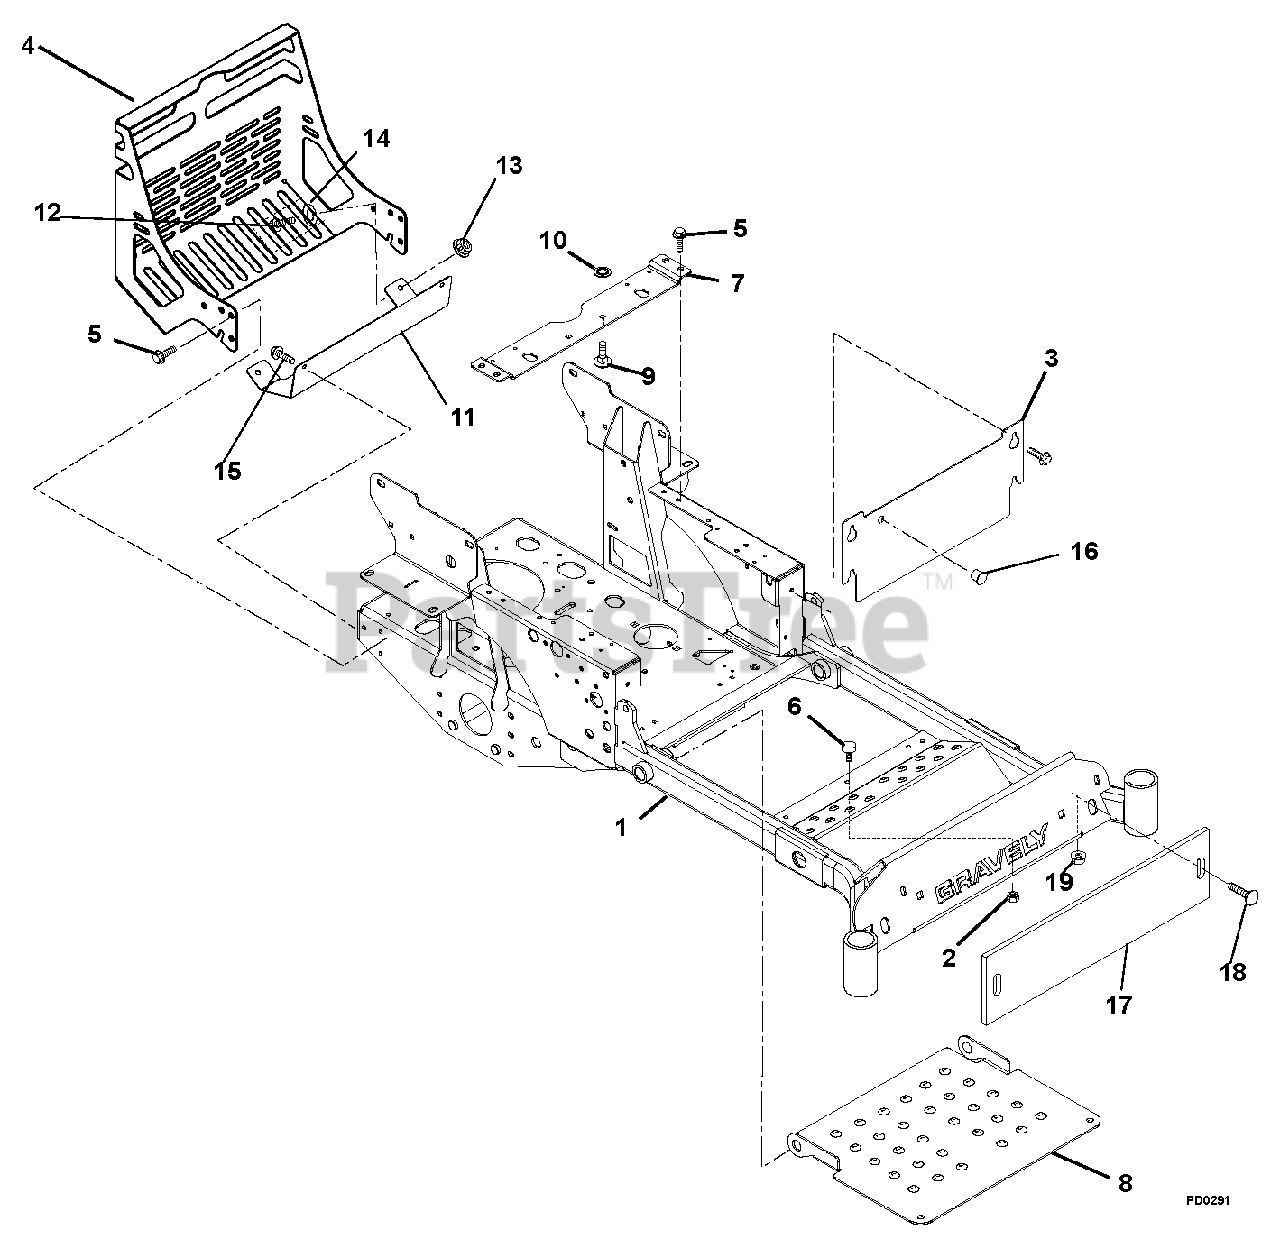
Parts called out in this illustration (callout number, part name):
1	Frame, Compact-Z
2	Nut, Spin Lock Flange .312-18
3	Access Panel
4	Bumper, Rear
5	Screw, Tapping .38-16 x .75 Hex Washer Head
6	Bumper, Rubber
7	Seat Support
8	Panel, Inspection
9	Bolt, Round Head Square Short Neck .31-18 x .75 Grade 5
10	Nut, Push .312
11	Heat Shield, Compact Z
12	Bolt, Hex .38-16 x .75 Grade 5
13	Nut, Nyloc Flange .38-16
14	Washer, Flat Steel .438 x 1.00 x .083
15	Screw, Tapping .38-16 x .50 Hex Washer Head
16	Plug, Hole .56
17	Counterwieght CZ Front- Red
18	Bolt, Round Head Square Neck .50-13 x 2.50 Grade 5
19	Nut .50-13 Nyloc Flange
